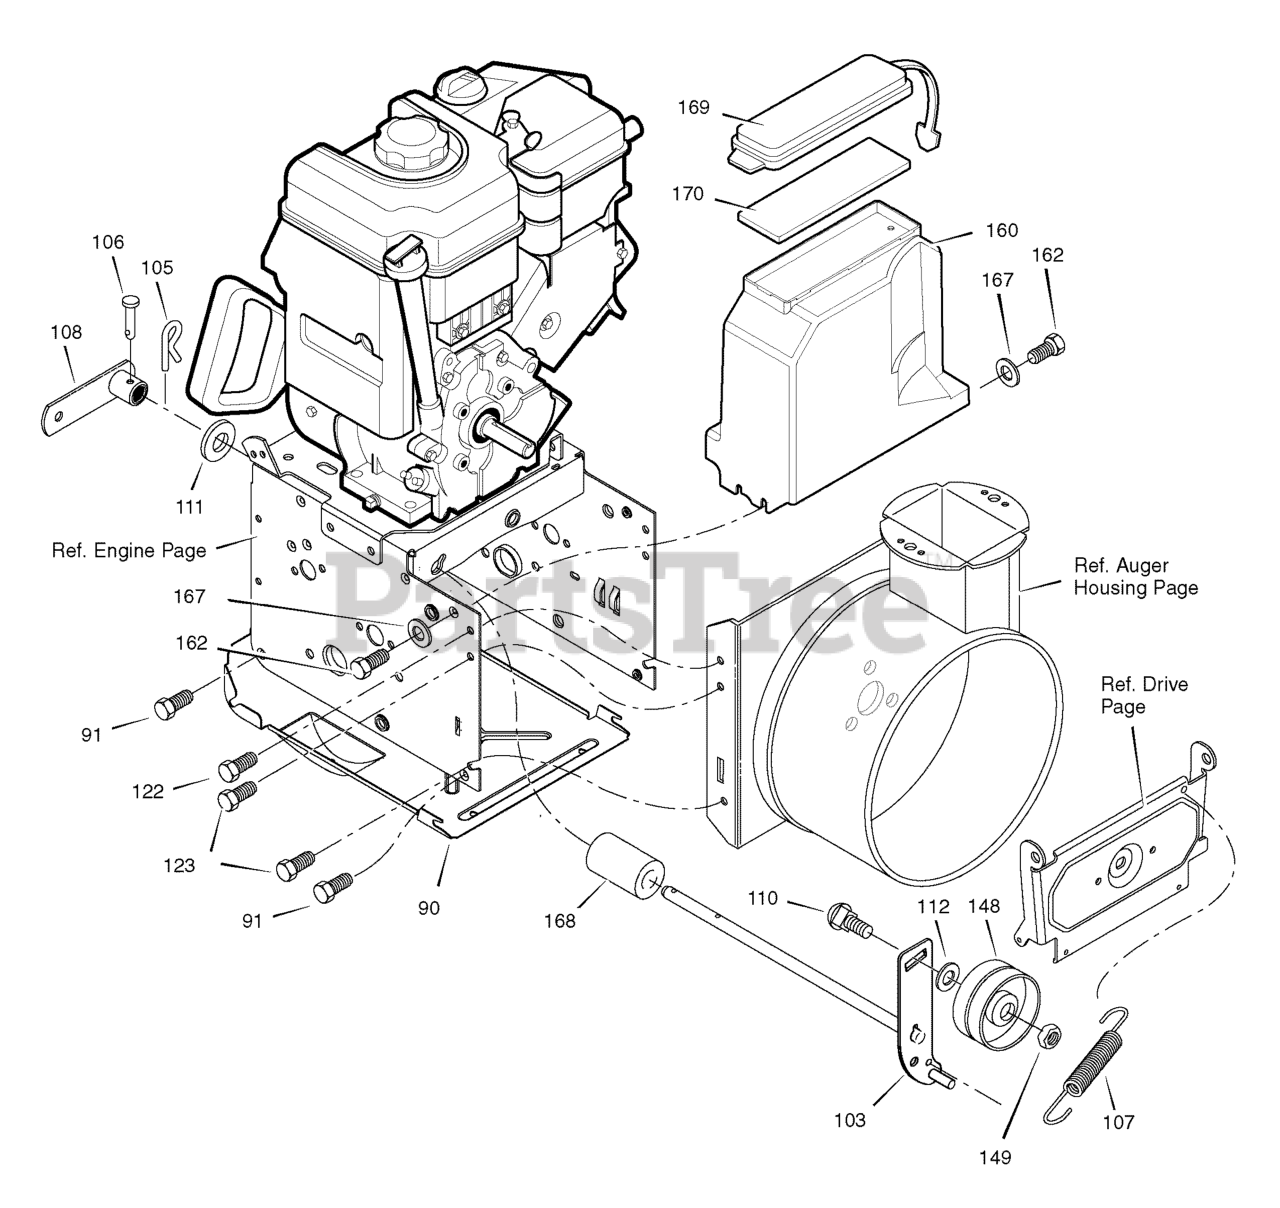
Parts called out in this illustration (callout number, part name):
90	COVER, BOTTOM
91	SCREW, 1/4-20 X 0.63
103	IDLER ASSEMBLY, AUGER
105	PIN, HAIR .38DIA X 1.64LG
106	PIN, CLEVIS 3/16" DIA
107	SPRING, TENSION
108	SPRING ATTACH ASSEMBLY
110	BOLT, 3/8-16 X 1.25 CARRIAGE
111	WASHER, FLAT
122	SCREW, TAP 5/16-18 X 0.50
123	SCREW, TAP 5/16-18 X 0.75
148	PULLEY, IDLER
149	NUT, JAM 3/8-16
160	COVER, BELT
162	SCREW, TAP
167	WASHER, FLAT
168	SPACER, AUGER BRACKET
169	LID, TOOL BOX
170	PAD, FOAM
